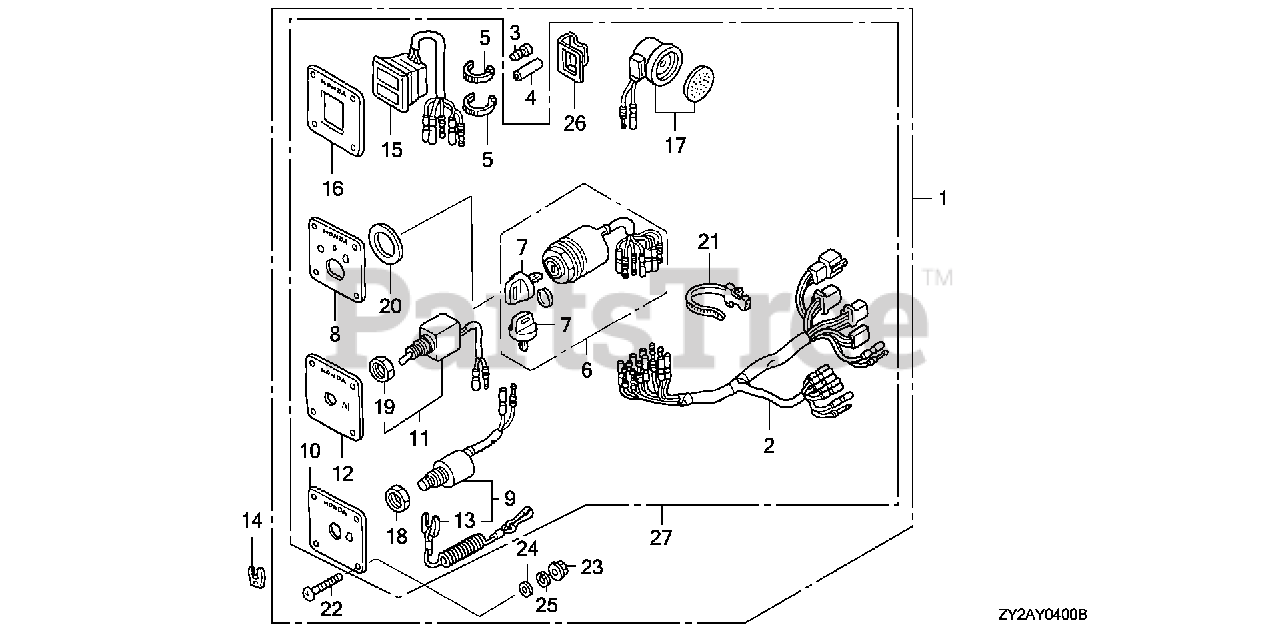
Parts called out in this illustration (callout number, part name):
2	HARNESS ASSY., SWITCH PANEL
3	PLUG, CONNECTOR (INNER)
4	PLUG, CONNECTOR (OUTER)
5	TIE, CABLE (2.4X92) (NATURAL)
6	SWITCH ASSY., COMBINATION
7	KEY ASSY., COMBINATION SWITCH (35100-ZV5-003 ONLY)
8	PANEL, SWITCH
9	SWITCH ASSY., EMERGENCY STOP
10	PANEL, EMERGENCY STOP SWITCH
11	SWITCH ASSY., SOLENOID
12	PANEL, SOLENOID
13	WIRE, EMERGENCY
14	CLIP, EMERGENCY LOCK
15	LAMP ASSY., INDICATOR (2-LED)
16	PANEL, INDICATOR
17	BUZZER, WARNING
18	NUT, HEX. (16MM)
19	NUT, HEX. (12MM)
20	WASHER, PLAIN
21	BAND, WIRE HARNESS (150MM) (NATURAL)
22	SCREW, PAN (5X40)
23	NUT, FLANGE (5MM)
24	WASHER, PLAIN (5MM)
25	WASHER, SPRING (5MM)
26	BRACKET, BUZZER
27	PANEL ASSY., CONTROL (TYPEB)
